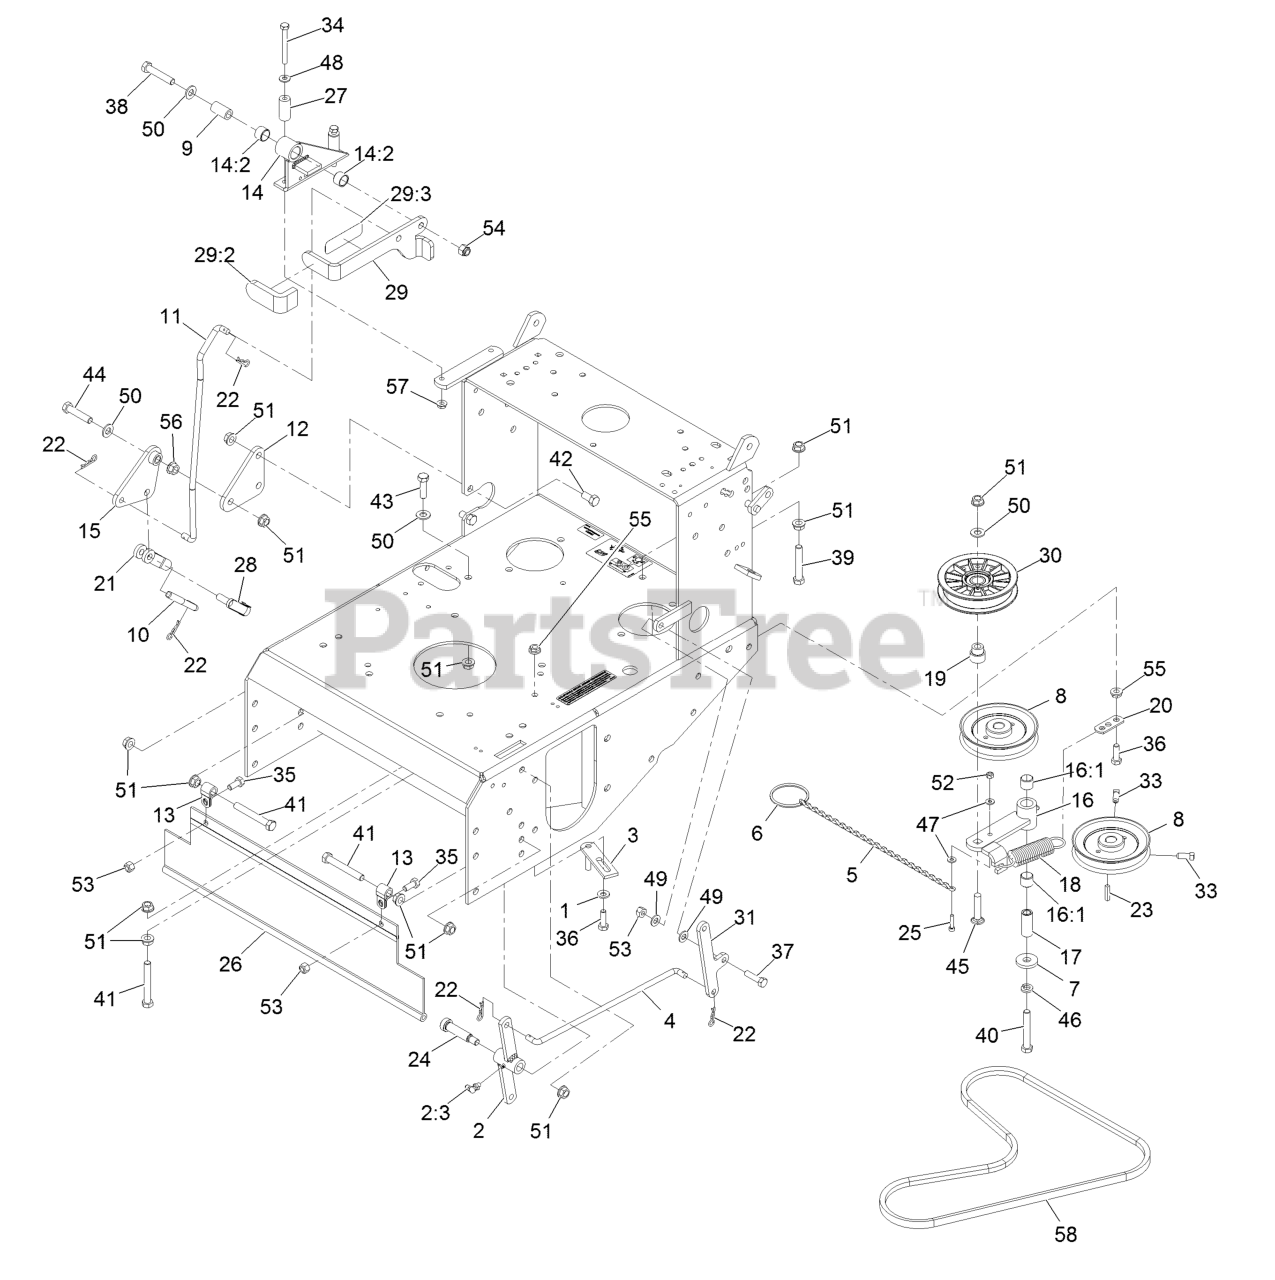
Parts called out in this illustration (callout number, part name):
1	WASHER-SPRING
2	BELLCRANK ASM
2:3	FITTING-GREASE, 90 DEG
3	GUIDE-BELT
4	LINKAGE-ENGAGE, BLADE
5	CHAIN-LINK, TWIST
6	RING-SPLIT
8	SHEAVE ASM
9	BUSHING-PIVOT
10	LINKAGE-LOWER
11	LINKAGE-UPPER
12	BELLCRANK
13	CLIP-LOOM
14	BRACKET ASM
14:2	SLEEVE-BUSHING
15	BELLCRANK ASM
16	IDLER ARM ASM
16:1	SLEEVE-BEARING
17	BUSHING
18	SPRING-EXTENSION
19	BUSHING-IDLER
20	ANCHOR-SPRING
21	YOKE-LINKAGE, BRAKE
22	PIN-COTTER
25	SCREW-HSH
26	SHIELD-DRAG
28	PIN-SPRING, CLEVIS
29	LEVER,PARK BRK W/DECAL
29:2	GRIP-LEVER
29:3	DECAL-PARKING BRAKE
30	PULLEY-IDLER, FLAT
31	BELLCRANK
33	SCREW-SET, SQH
34	SCREW-HH
35	SCREW-HH
36	SCREW-HH
37	SCREW-HH
38	SCREW-HH
39	SCREW-HH
40	BOLT-CARR
41	SCREW-HH
42	SCREW-HH
43	SCREW-HH
44	SCREW-HH
45	SCREW-CARR
46	WASHER-LOCK
47	WASHER-FLAT
48	WASHER-FLAT
49	WASHER-PLAIN
50	WASHER-FLAT
51	NUT-HHF, WHIZ
52	NUT-LOCK, NI
53	NUT-LOCK, NI
54	NUT-LOCK, NI
58	BELT-COG
